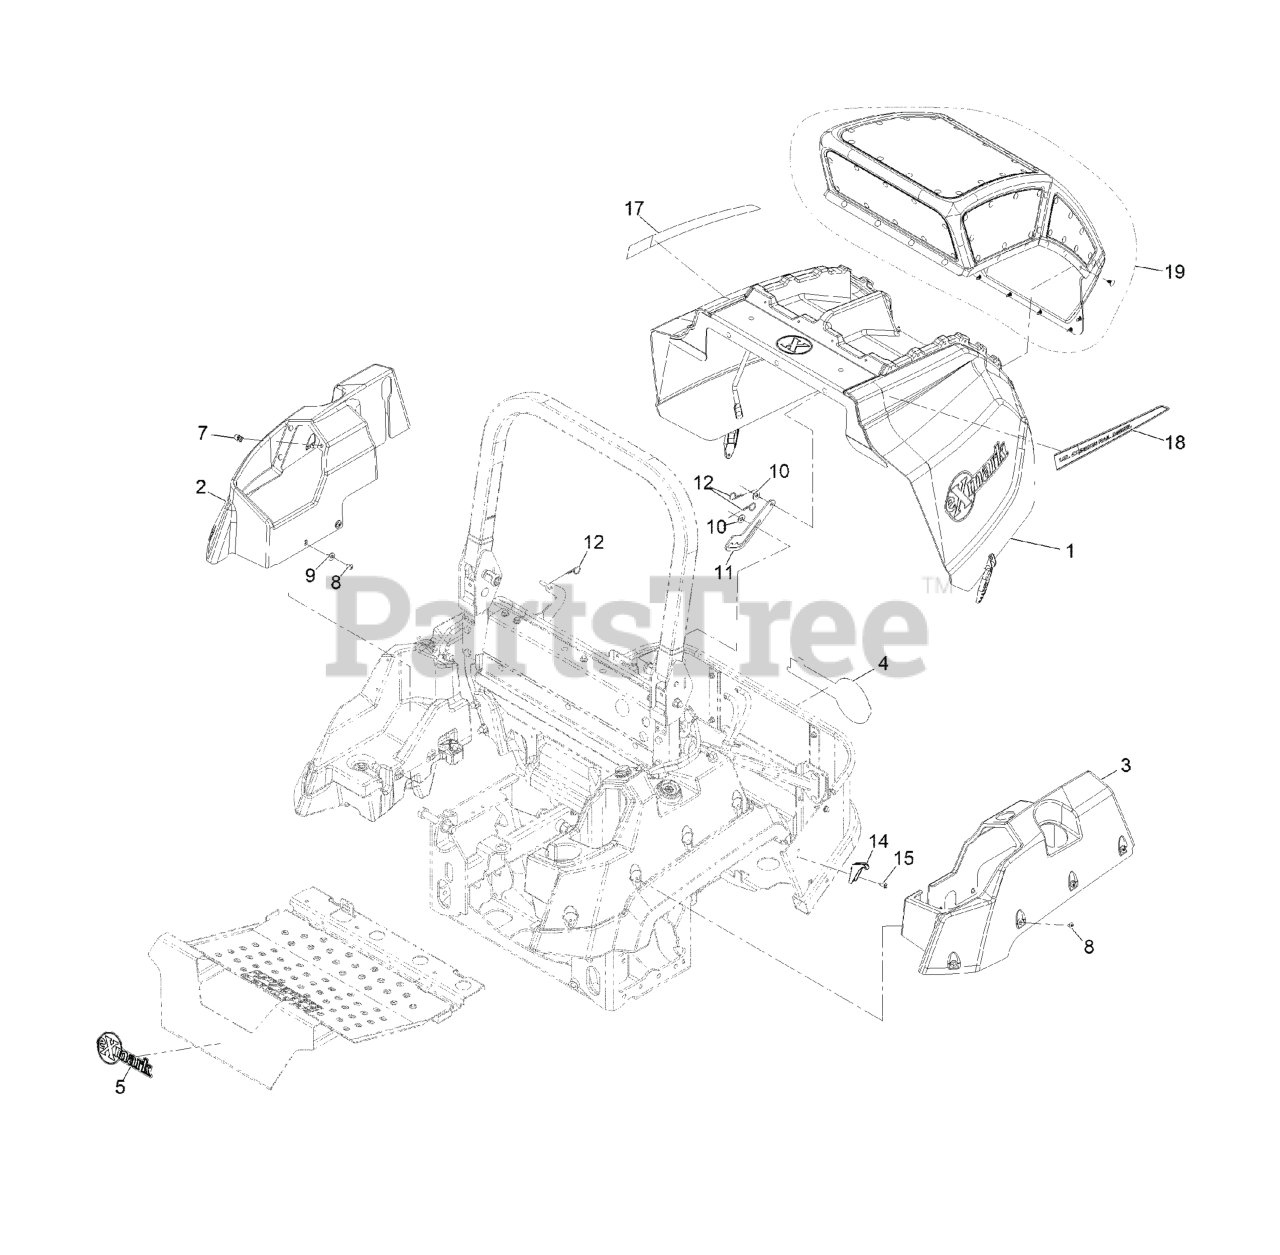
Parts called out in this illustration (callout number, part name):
1	ASM, HOOD LZSD
2	COVER-TANK, RH
3	COVER-TANK, LH
4	DECAL-EXMARK
5	DECAL-EXMARK
8	SCREW-TORX
9	WASHER-FLAT
10	WASHER-FLAT
11	PROP-HOOD
12	PIN-COTTER, HAIR
14	LATCH-CATCH
15	SCREW-HWH
17	DECAL-COMMON RAIL DIESEL-RH
18	DECAL-COMMON RAIL DIESEL-LH
19	ASM, HOOD-INTAKE
